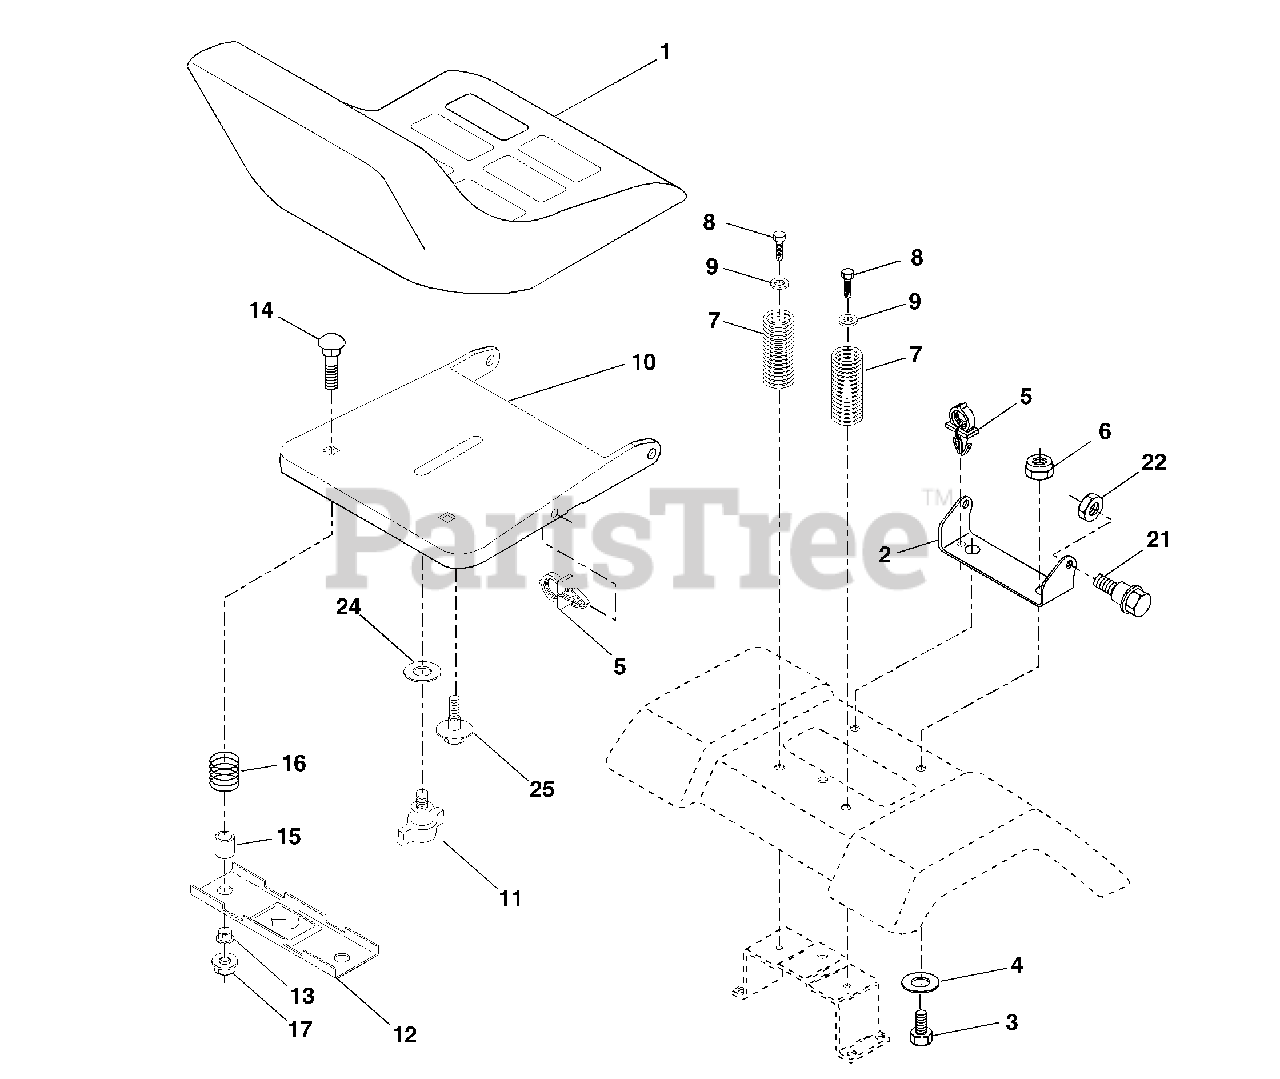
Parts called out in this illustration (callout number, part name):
1	Seat
2	Bracket Pivot Seat 8 720
3	Bolt Fin Hex 3/8-16 Unc x 1
4	Washer Flat 13/32 x 1 x 10 Ga.
5	Clip Push-In
6	Nut Hex w/Ins. 3/8-16 Unc
7	Spring Seat Cprsn 2 250 Blk Zi
8	Screw 3/8-16 x 1
9	Washer 13/32 x 1 x 14 Ga.
10	Pan Seat
11	Knob Seat Adj. Wingnut
12	Bracket Mounting Switch
13	Bushing Snap Blk Nyl 50 Id
14	Bolt Rdhd Sqnk 1/4-20x1-1/2
15	Spacer Split 28x 88
16	Spring Cprsn
17	Nut Lock 1/4 Lge Flg Gr 5 Zinc
21	Bolt Shoulder 5/16-18 Unc
22	Nut Hex Lock W/Ins 5/16-18
24	Washer 17/32 X 1-3/16 X 12 Ga.
25	Bolt Shoulder 5/16-18 X 62
